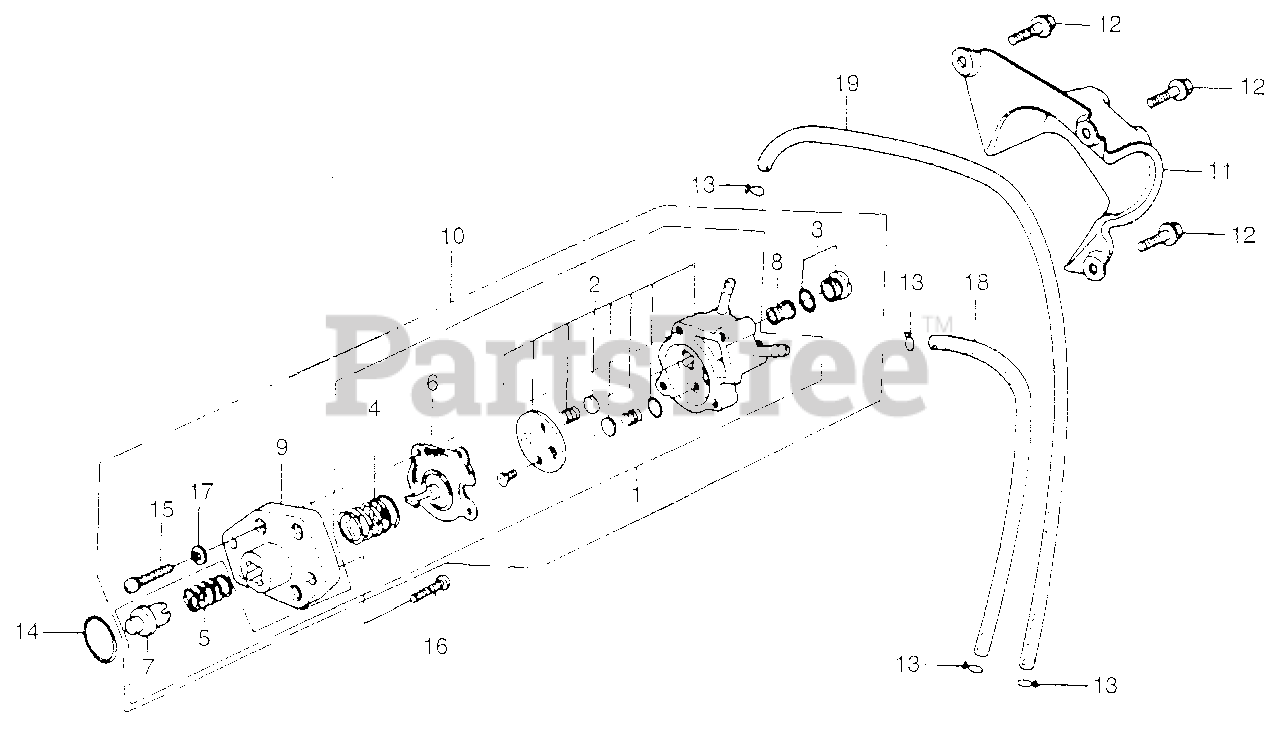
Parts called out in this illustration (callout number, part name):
1	PARTS SET, FUEL PUMP (NOT AVAILABLE)
2	BODY SET, PUMP (NOT AVAILABLE)
3	BOLT SET, HOLDING
4	SPRING, DIAPHRAGM (NOT AVAILABLE)
5	SPRING, PUSH ROD (NOT AVAILABLE)
6	DIAPHRAGM (NOT AVAILABLE)
7	ROD, PUSH
8	SCREEN, FUEL STRAINER
9	BODY (LOWER) (N/A: SEE ASSEMBLY)
10	PUMP ASSY., FUEL (NOT AVAILABLE)
11	COVER, FUEL PUMP
12	BOLT, FLANGE (6X28)
13	CLIP, TUBE (B8)
14	O-RING (20.8X2.4)
15	SCREW, PAN (4X20)
16	SCREW, PAN (6X20)
17	WASHER, SPRING (4MM)
18	BULK HOSE, FUEL (4.5X3000) (4.5X320)
19	BULK HOSE, FUEL (4.5X3000) (4.5X400)
